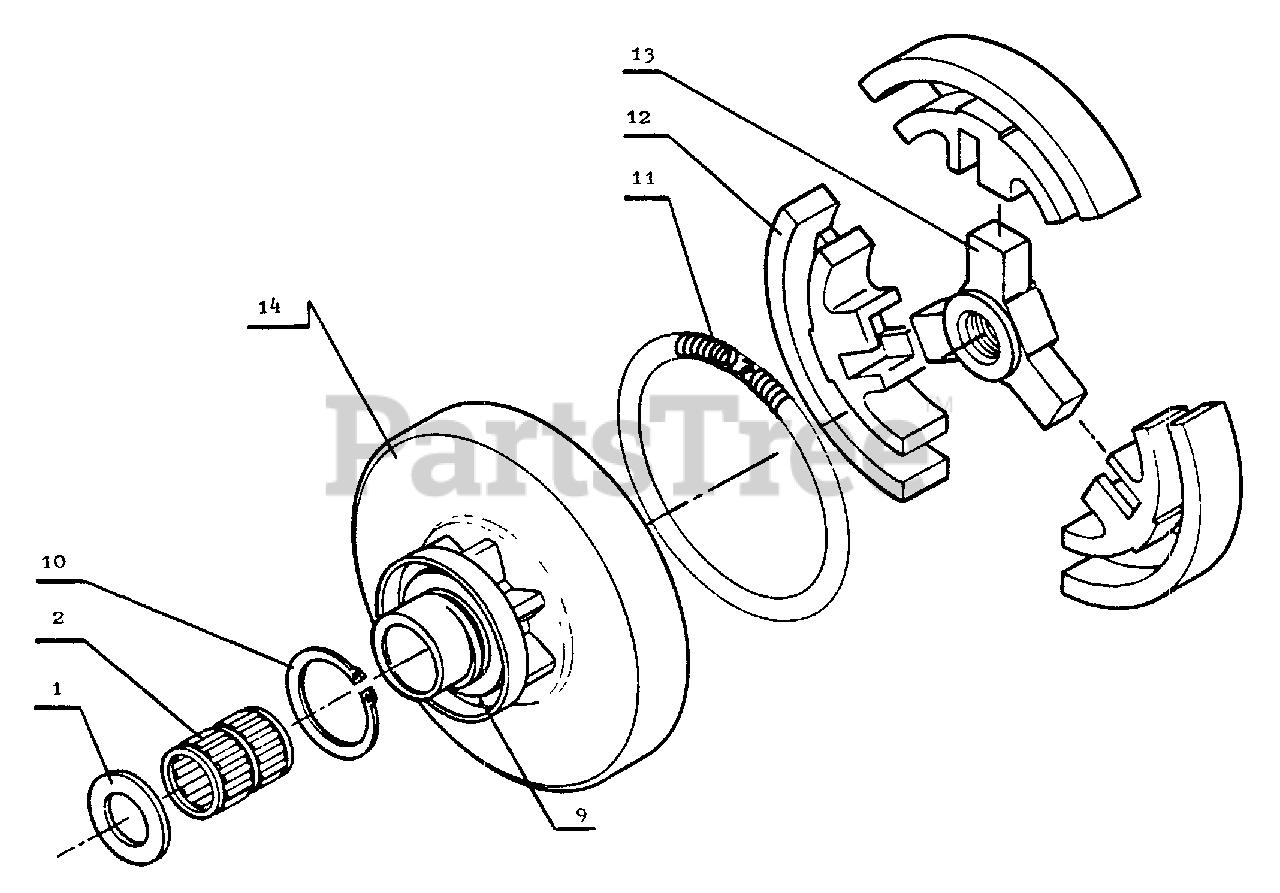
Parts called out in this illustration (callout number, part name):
1	WASHER, CLUTCH
2	BEARING, NEEDLE
9	SPACER
10	RING, RETAINING - 20
11	SPRING, CLUTCH
12	SHOE, CLUTCH
13	HUB, CLUTCH
14	CASE, CLUTCH
